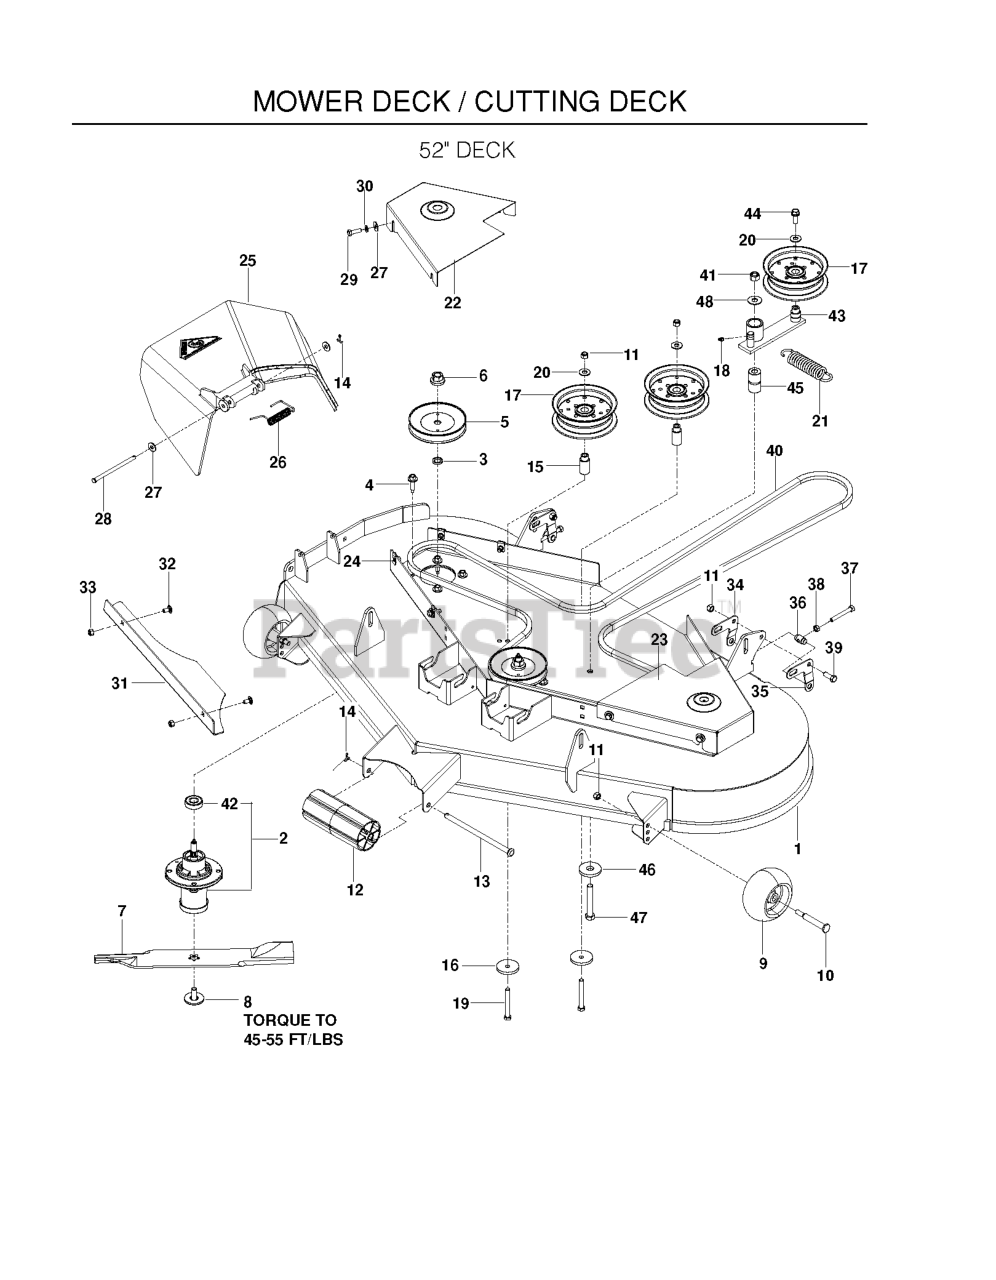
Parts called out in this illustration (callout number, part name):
1	DECK W/DECALS 52
2	HOUSING ASM
6	LOCKNUT - 9/16
7	BLADE, 18"
8	BOLT.WASHER.ASM.7/16-2
10	SHOULDER BOLT 1/2X2-5/8 ZD SPE
11	NUT 3/8-16 NYLOC
12	NOSEROLLER 48"
13	NOSE ROLLER ROD
14	COTTER PIN 1/8 X 3/4
15	IDLER BUSHING
16	SPINDLE WASHER
17	PULLEY, IDLER
18	ZERK
19	HCS 3/8C X 3
20	WASHER 3/8 FLAT
22	SHIELD, BELT 52 BLUE RH
23	SHIELD, BELT 52 BLUE LH
24	U-CLIP 5/16-18 NUT RETAINER
25	DISCHARGE CHUTE 52"
26	SPRING - TORSION
27	WASHER 5/16 FLAT
28	PIN-CLEVIS 5/16 DIA X 5.19 ZD
29	HCS 5/16C X 1
31	CONFINEMENT PLATE, 52"
32	CARRIAGE BOLT 5/16C X 5/8"
33	NUT 5/16 NYLOC
34	PITCH, ADJUST, RT
35	PITCH, ADJUST, LT
36	TRUNION, PITCH
37	HCS 5/16-18 X 2 1/2 TPBLT
38	NUT 5/16C HEX
39	HCS 3/8C X 1
40	BELT, B, 148.5
41	NUT 1/2-13 HEX NYLOC ZD
42	BEARING, BALL
43	IDLER ARM
44	HCS 3/8C X 1 SERRATED HEAD
45	PIVOT BUSHING
46	WASHER, SUPPORT
47	HCS 1/2C X 3 1/4
48	WASHER 1/2 FLAT
